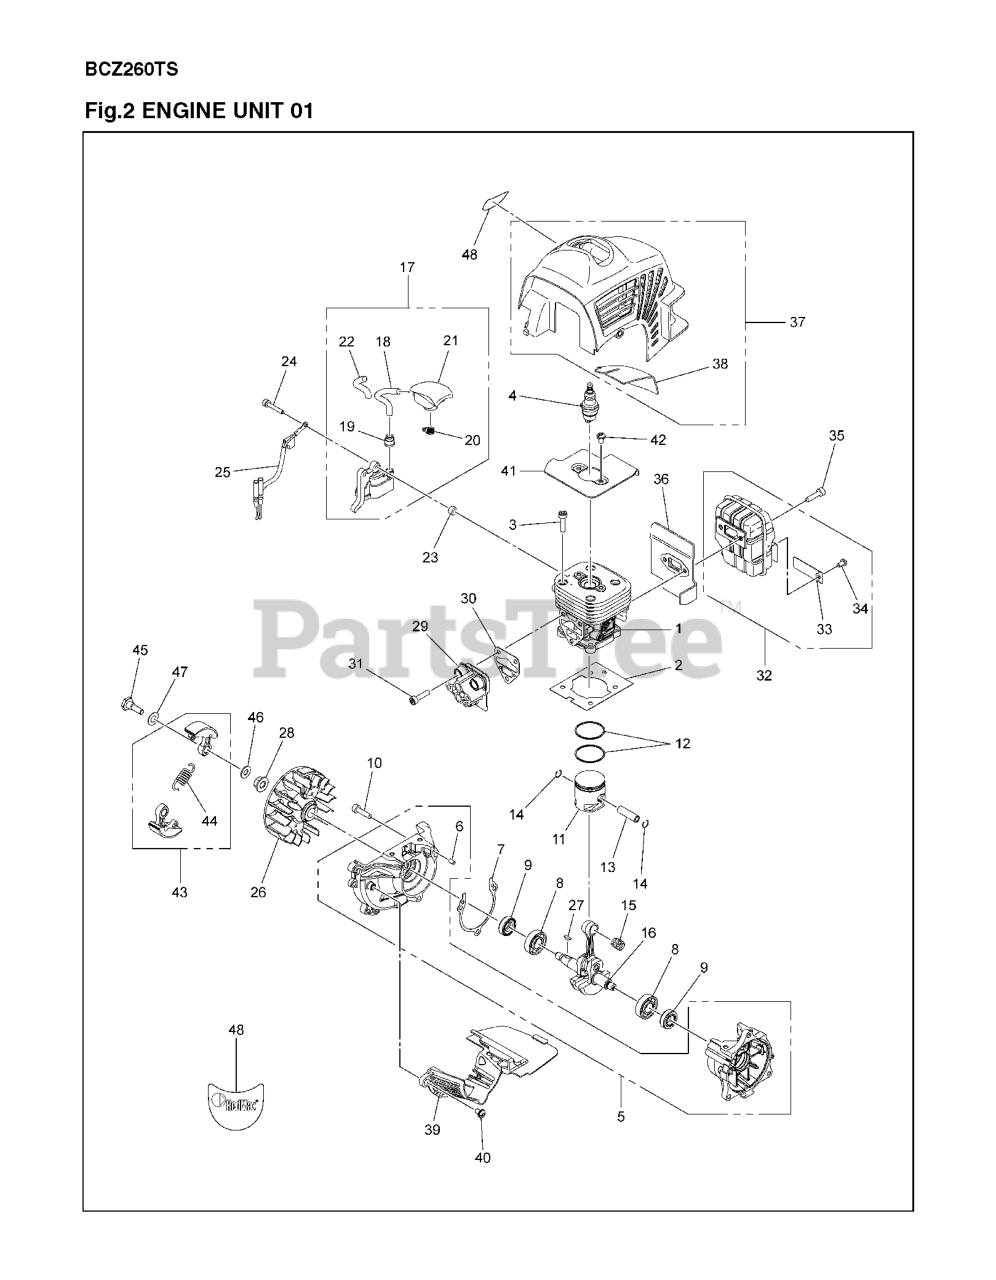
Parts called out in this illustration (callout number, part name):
1	CYLINDER COMP
2	GASKET BASE
4	SPARK PLUG, BPMR8Y
5	CRANKCASE ASSY
7	GASKET CASE
13	PIN
16	CRANKSHAFT COMP
17	IGNITION MODULE
18	IGNITION CABLE
19	HUB CAP 848F6L71E0
21	SPARK PLUG CAP
22	TUBE (RPLS 263072210)
23	SPACER
24	BOLT M4 X 25
25	SHORT CIRCUIT CABLE
26	FLYWHEEL
27	KEY
28	NUT
29	INSULATOR
32	MUFFLER ASSY
33	SPARK ARRESTER
34	SCREW CRPANT TYPE F ST4.2X9.5
36	GASKET MUFFLER
37	CYLINDER COVER COMP
38	SHEET HEAT INSULATION
39	PLATE MUFFLER
41	PLATE CYLINDER
43	CLUTCH ASSY
44	CLUTCH SPRING
48	DECAL BRAND
